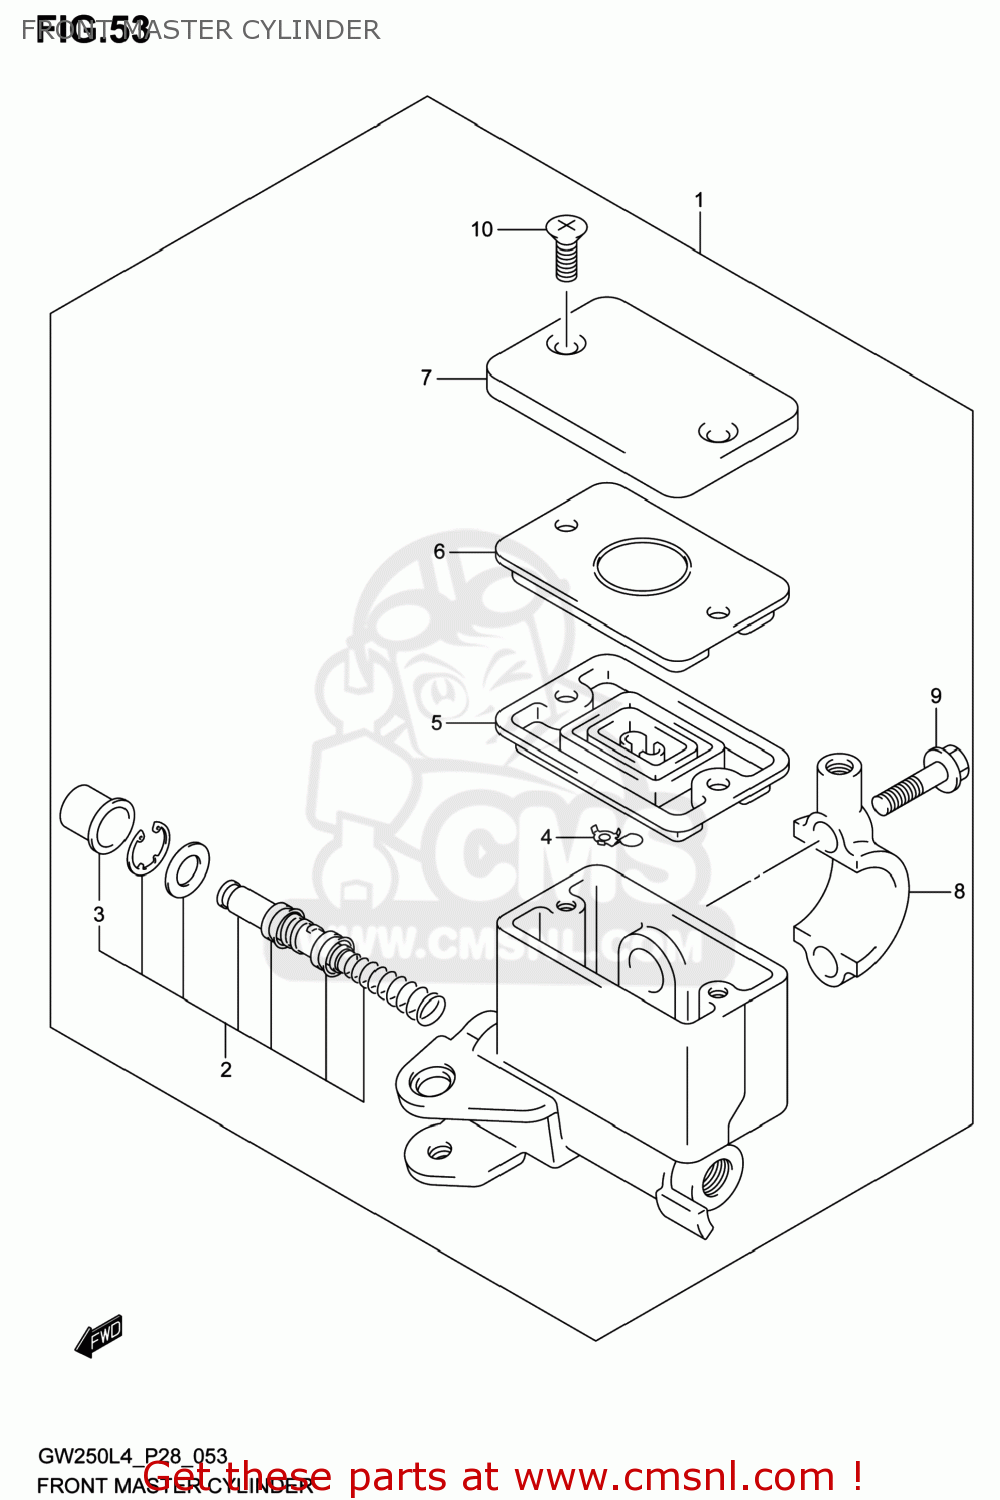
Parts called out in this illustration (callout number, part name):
1	CYLINDER ASSY,FR MASTER
2	PISTON & CUP SET
3	BOOT
4	PROTECTOR
5	6
6	PLATE,DIAPHRAGM
7	CAP
8	HOLDER
9	BOLT(6X22)
10	SCREW
